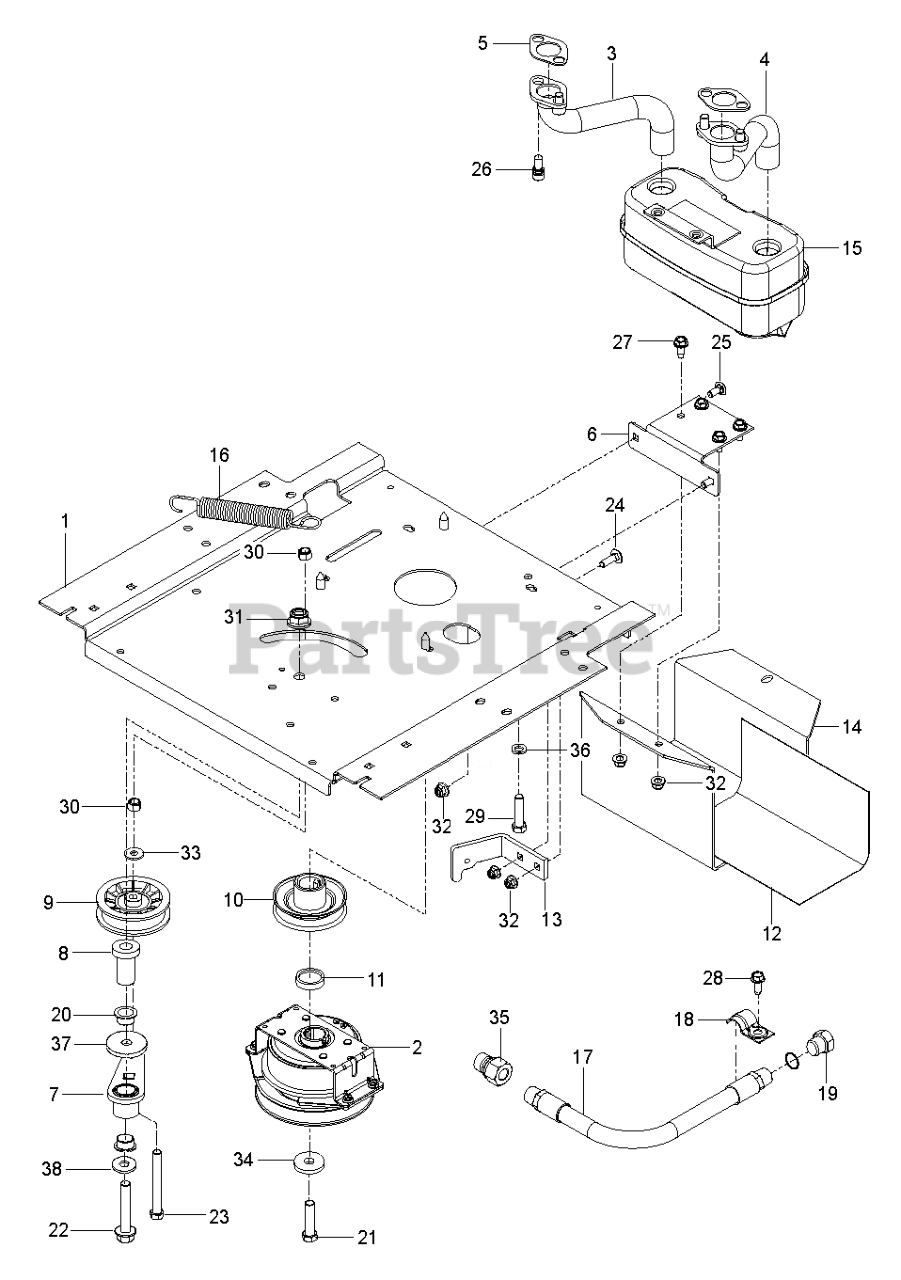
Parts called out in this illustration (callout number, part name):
1	PLATE.ENGINE.PNT.23"FRAME.EDIP
2	CLUTCH.OGURA.5.0PD.GT1.5A-EH07
3	EXHAUST.TUBE.LH.BS/TWIN
3	PIPE.EXHAUST.RH.CV18/20
3	TUBE.EXHAUST.RH.FR961/FR730
3	EXHAUST.TUBE.RH.B&S.TWIN.INTEK
4	EXHAUST.TUBE.LH.BS/TWIN
4	PIPE.EXHAUST.LH.CV18/20
4	EXHAUST.TUBE.RH.B&S.TWIN.INTEK
4	TUBE.EXHAUST.LH.FR961/FR730
5	GASKET.MUFFLER
5	GASKET
6	BRACKET MUFFLER MS431BLK
7	ARM IDLER
8	IDLER SPINDLE
8	SPINDLE.IDLER
9	PULLEY, IDLER RAKE & ZTR
10	PULLEY.ENGINE
11	SPACER.SPACER.625 W/OGURA.LCC
12	HEAT SHIELD
13	CLUTCH.STOP.OGURA LCC.BLACK
14	GUARD.MUFFLER.WO.TOW.HITCHX431
15	MUFFLER ASM TWIN
16	SPRING, DECK DRIVE
17	HOSE.ASSEMBLY.OIL.DRAIN
18	CLAMP
19	PLUG OIL DRAIN
20	BEARING.FLANGED.PLASTIC.3/4ID
21	CLUTCH BOLT7/16-20X2.5 GR524HR
21	CLUTCH BOLT7/16-20X3.5 GR524HR
22	HCS 1/2-13 X 3-1/4 GD 5 ZD
22	BOLT.FLANGE.1/2-13 X 2.75.GRD5
23	HCS 3/8-16X3-1/2 TAPBLT GR5 ZD
24	BOLT
24	RHSNB 5/16C X 1
25	RP BOLT 5/16-18 X3/4 ZN/YEL GR
25	BOLT 5/16C X 3/4" CARRIAGE
26	SCREW.SOCKET HD.5/16-1
26	SCREW.SOCKET.HEAD.5/16-18
27	SCREW.THDROL.5/16-18X3/4.TTY
28	SCR 1/4-20X5/8 HEX SELF TAP ZD
29	NUT 3/8-16 NYLOC
29	SCREW 3/8-16X1
29	BOLT
30	NUT 3/8-16 NYLOC
30	NUT, 1/2-13 HEX FLG NYLOC ZD
31	NUT.LK.W/WSH.1/2.
31	NUT, 1/2-13 HEX FLG NYLOC ZD
31	5/16-18 NYLOC FLANGE NUT
32	5/16-18 NYLOC FLANGE NUT
32	NUT 3/8-16 NYLOC
33	WASHER.5/16.FLAT.STE.STD.
33	WASHER 5/16 FLAT
35	ADAPTER, OIL DRAIN
36	LOCKWASHER
37	HEAVY WASHER
38	WASHER.9/16 X 1 3/8 X 12 GA.
